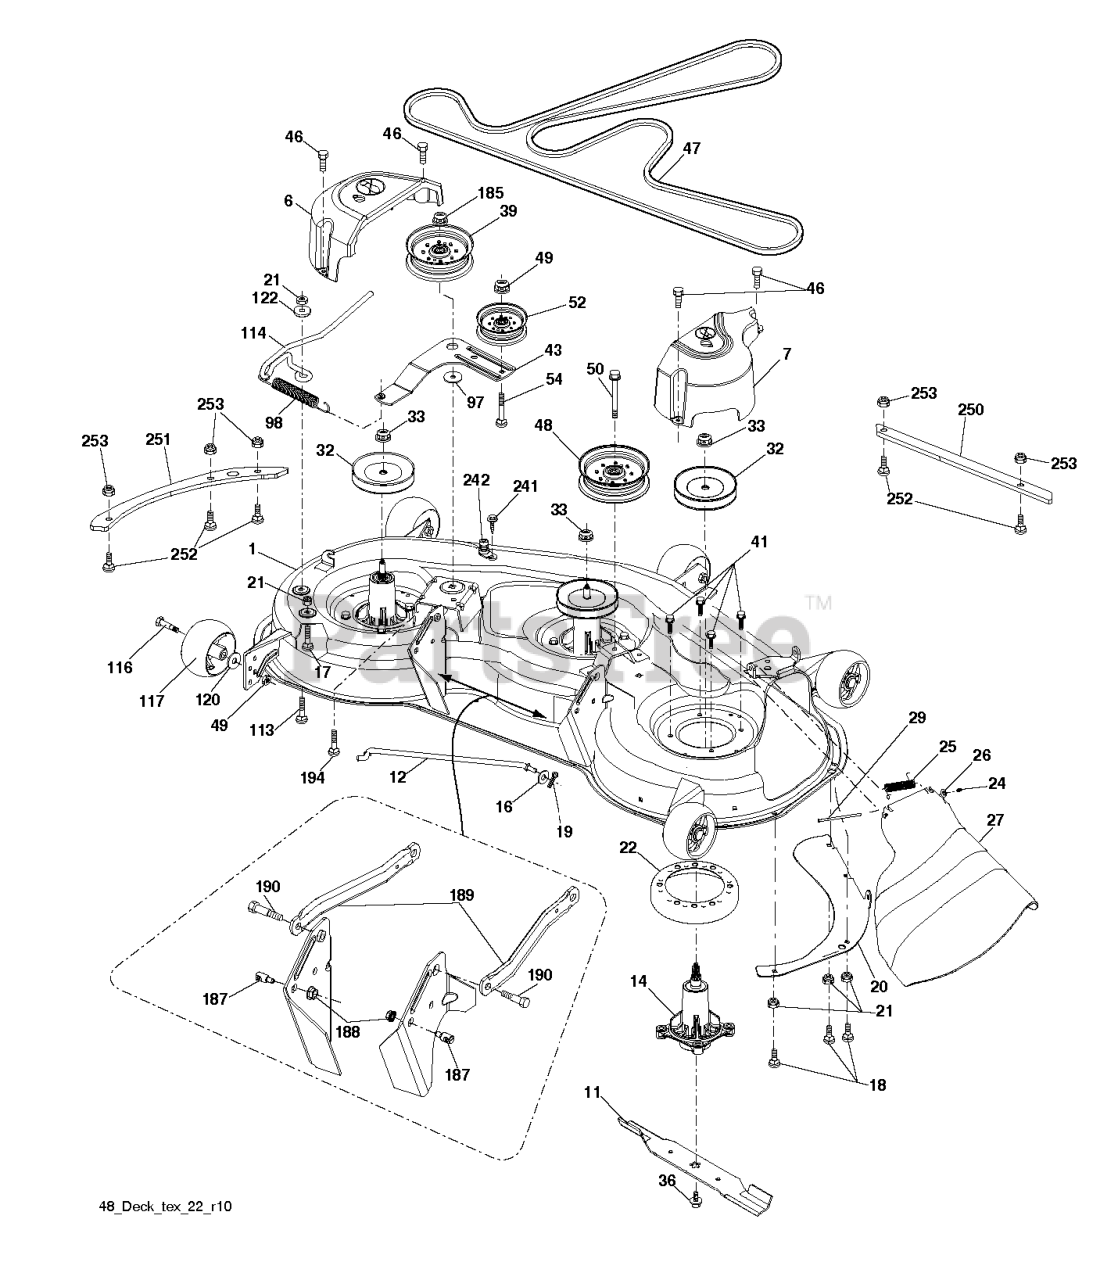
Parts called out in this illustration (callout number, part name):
1	DECK.SVC 48".4GWB.O
6	COVER.MANDREL.LH.48"(2 2)
7	COVER.RH.MANDREL
11	48" HI-LIFT BLADE
12	ROD.ANTI.SWAY.48/54"K4
14	KIT.MANDREL.GREASEABLE.TALL
17	Bolts
18	BOLT ROUND HEAD SQUARE NECK BO
19	PIN.COTTER.5/16.BOW TI
20	BAFFLE, VORTEX MWR
21	GSPW Nuts
22	STRIPPER.MANDREL.ROUND.BLACK
24	CAP-SLEEVE LT
25	SPRING, TORSION
26	NUT PUSH M
27	DEFLECTOR SUBS TO 532 180655
32	PULLEY MANDREL
36	SCREW.SEMS.7/16-20X1.HEX.HEAD
39	RB PULLEY.IDLER.4.50/HUB SPEC
41	BOLT.HEX.WASHR.HED.313-18X1.19
46	SCREW.1/4-20X5/8
47	Belts- 197242
48	PULLEY.IDLER.2006
49	NUT LOCK FLG 3/8-16 UNC
50	SCREW TT 3/8-16X2-1/4 UNC
50	SCREW TT 3/8-16X2.31 UNC
52	PULLEY.IDLER.48"PRIMARY
54	GSPW Bolts
98	SPRING, DECK DRIVE
114	ROD.TENSION.RELIEF.TEX (2 2)
117	WHEEL.GAUGE.RALLY
122	BUSHING.RELIEF.TENSION
185	NUT.LOCK.FLANGE.7/16
187	STUD.W/"D"ANTI-ROTATION
187	STUD.FASTNER.W/ANTI-ROTATE
189	ARM.RFIXED.MOWER.SUSPNSIONX431
190	BOLT.SHOULDER
194	BOLT.HEX.WASHER.HEAD.7/16-24X
241	SCREW.TT.#10-32X.5.3/8.FLANGE
242	PORT.WASHOUT
250	PLATE.REIN.FRNT.BOLTON.48X431
251	PLATE.REIN.SIDE.BOLT.ON.48X431
252	BOLT CUP HEAD SQUARE NECK 1/4-
253	NUT T
